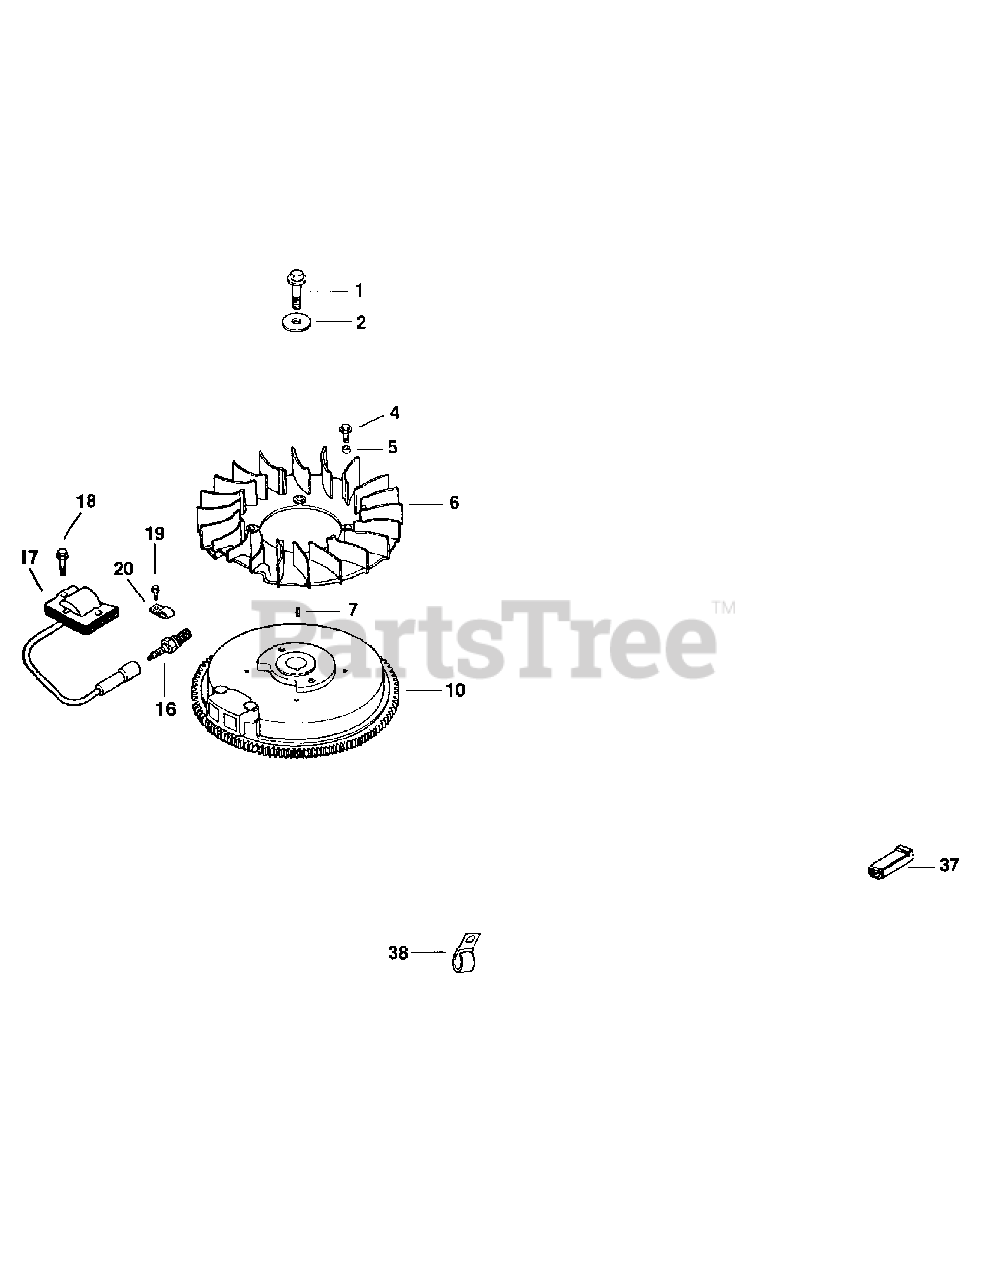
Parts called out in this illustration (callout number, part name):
1	Screw, Hex Flange
2	Washer, Plain 3/8"
4	Screw, Hex Flange
5	Spacer, Fan
6	Fan, Flywheel
10	Flywheel
13	Screw, Hex Flange
16	Spark Plug
17	Module, Ignition
18	Screw, Hex Flange
19	Screw, Hex Flange
20	Clip, Kill Lead
22	Cup And Screen
37	Connector
